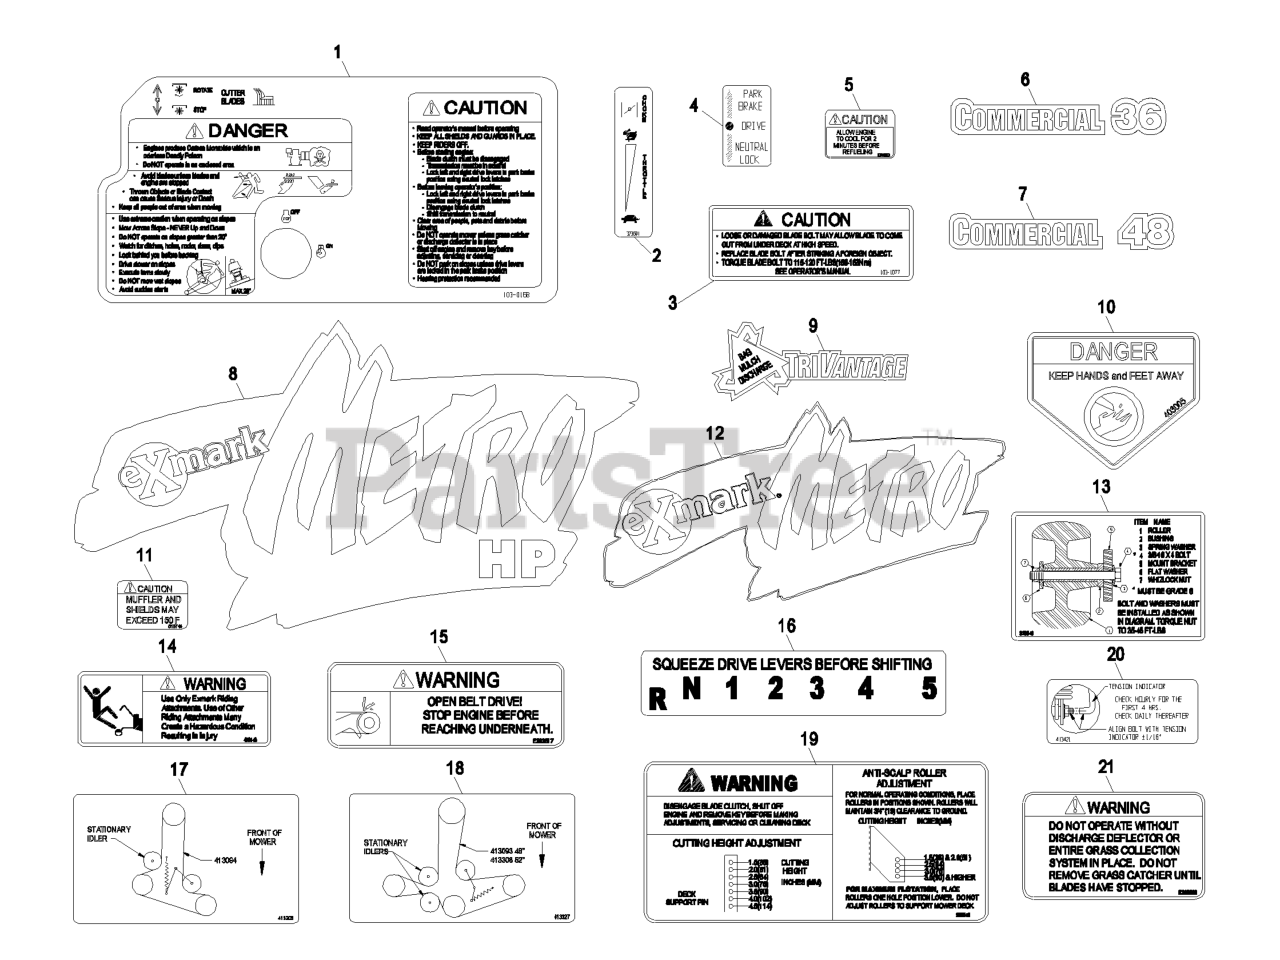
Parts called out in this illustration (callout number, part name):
2	DECAL,THROTTLE
3	DECAL,BOLT TORQUE
4	DECAL,NEUTRAL/BRAKE
6	DECAL,COMMERCIAL 36
7	DECAL,COMMERCIAL 48
10	DECAL-DANGER
13	DECAL,ROLLER MOUNTING
14	DECAL,SULKY WARNING
15	DECAL,BELT DRIVE
16	DECAL,SHIFTER
17	DECAL,BELT ROUTING
18	DECAL,BELT ROUTING
19	DECAL,ANTI SCALP
20	DECAL,INDICATOR
21	DECAL-WARNING, DISCHARGE
